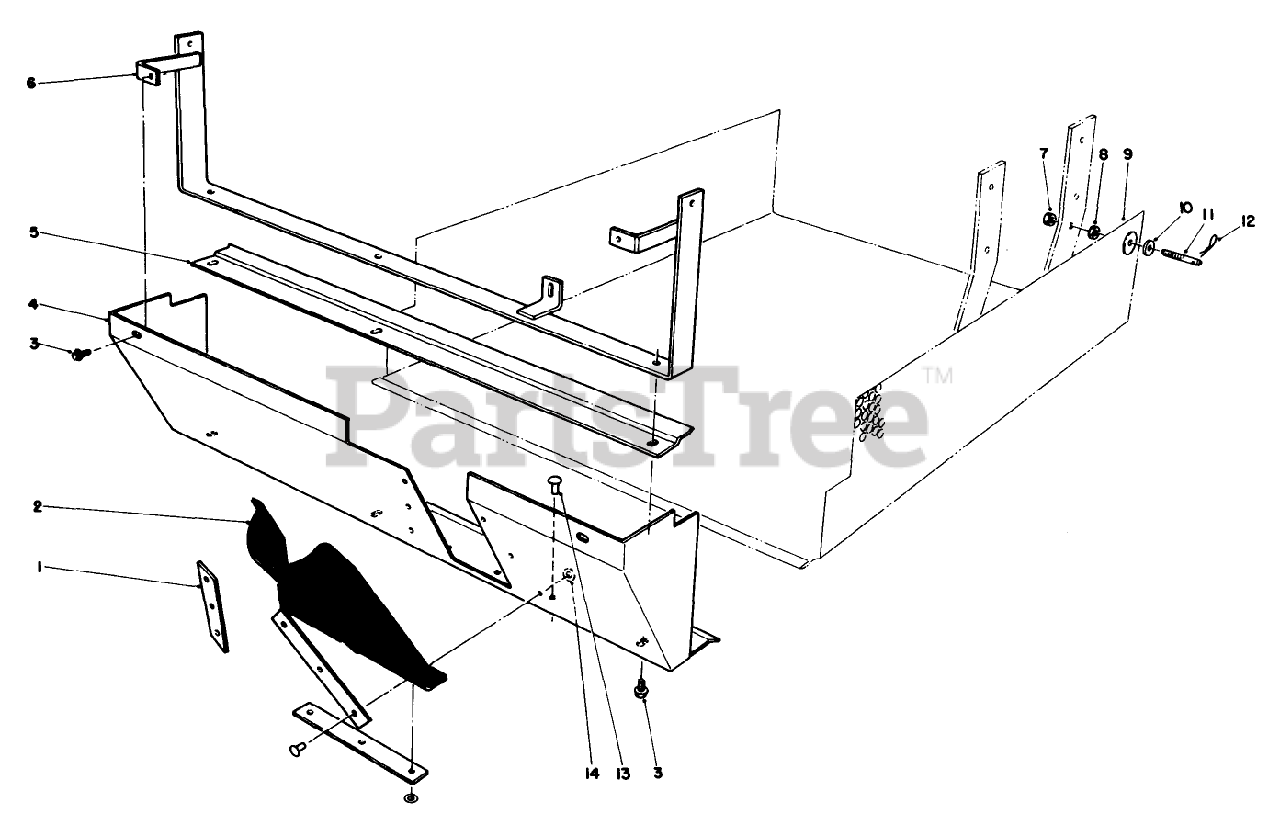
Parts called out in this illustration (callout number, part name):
1	RUBBER SUPPORT
2	RUBBER SHIELD
3	SCREW
4	Deflector
5	SCREEN SUPPORT B
6	DEFLECTOR MT WA R
7	NUT-LOCK, NI
8	NUT-JAM
9	GRASS SCREEN WA
10	WASHER-FLAT
11	SPECIAL STUD
12	PIN-COTTER, HAIR
13	RIVET-POP
14	WASHER-FLAT
